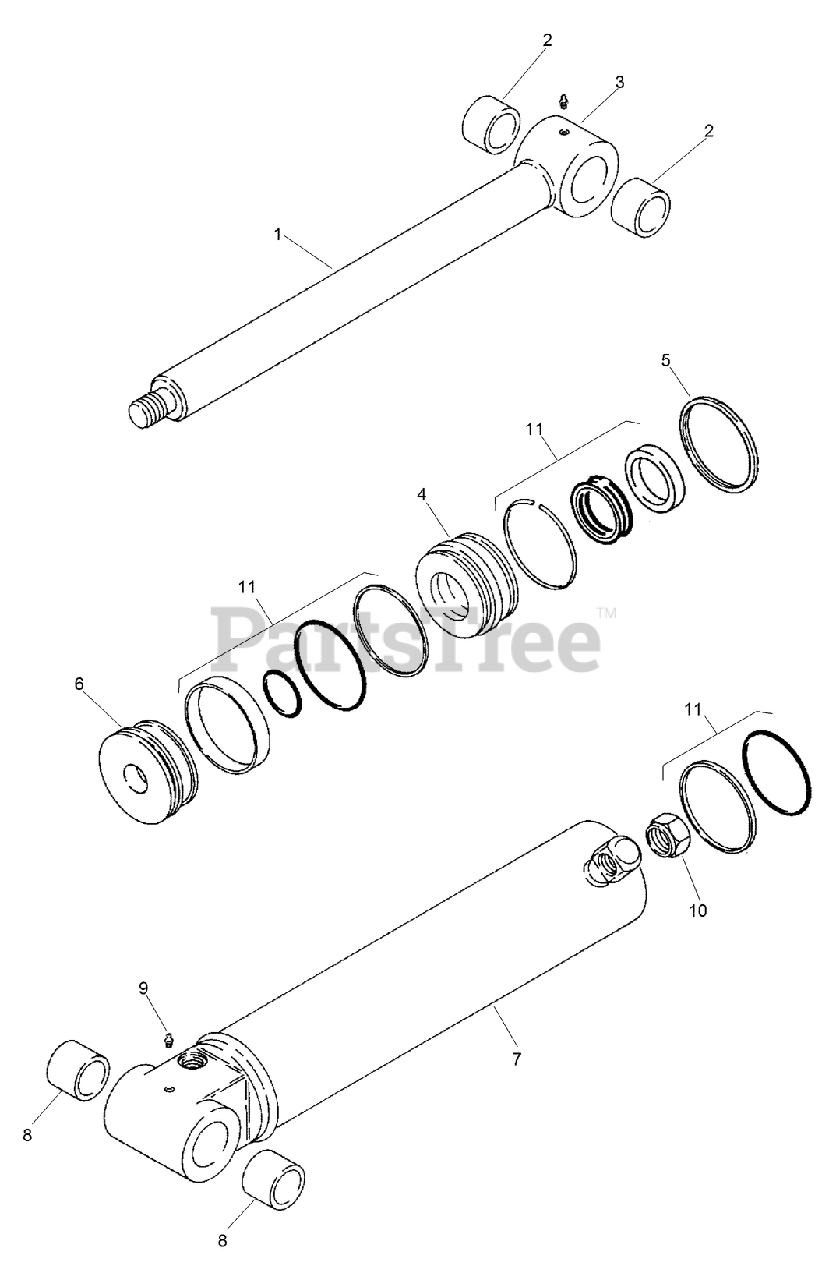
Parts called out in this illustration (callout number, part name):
1	ROD - Piston
2	BUSHING - Piston, Rod
3	FITTING-Lube 1/4-28 Tpr SAE-LT .54 Long
4	GLAND - Cylinder
5	NUT - Special
6	PISTON - Cylinder
7	Tube
8	BUSHING - Piston Rod
9	FITTING-Lube 1/4-28 Tpr SAE-LT .54 Long
10	NUT - Lock - 1-1/4 NF
11	KIT - Repair, Seal
